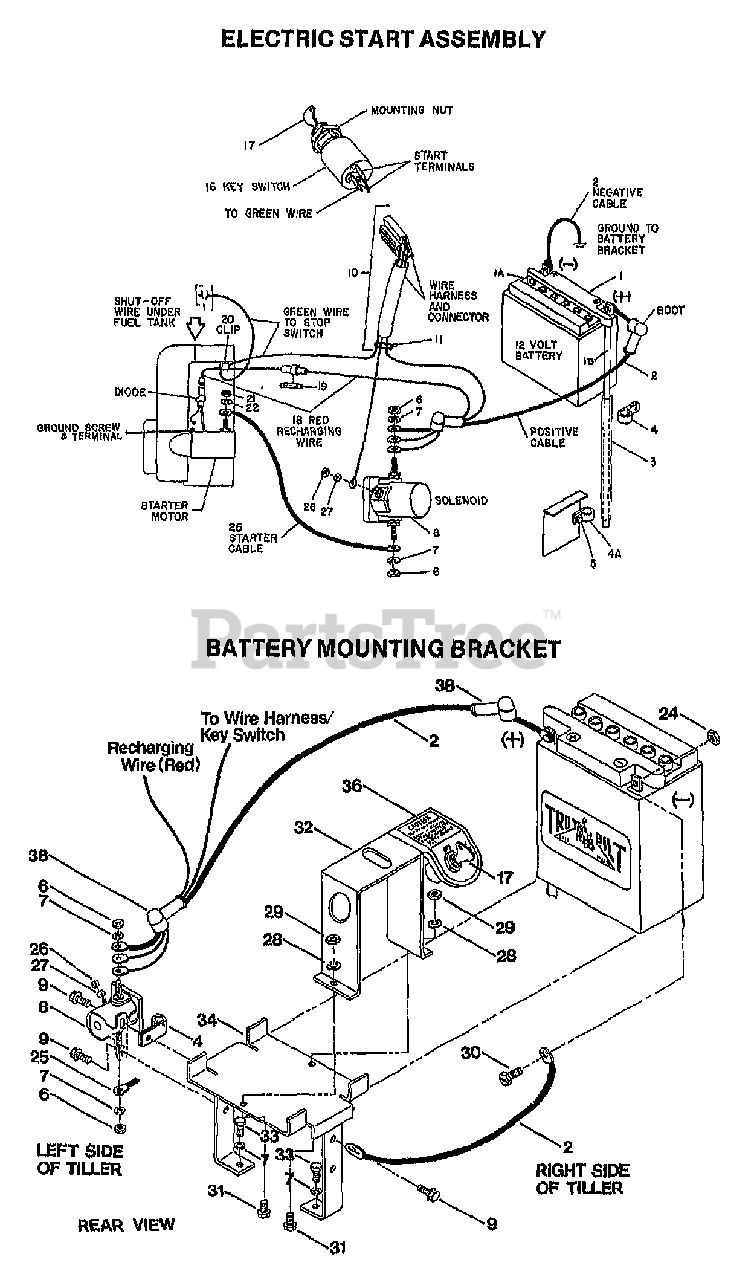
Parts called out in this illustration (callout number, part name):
1	BATTERY (INCL. HARDWARE TO CONNECT BATTERY CABLE TERMINALS TO BATTERY POSTS)
1A	CAP-YELLOW
1A	CAP-BATTERY WHITE (PONY)
1B	TUBE-VENT BATTERY/HSE
2	CABLE-BATTERY (REPLACES #9223)
3	TUBING-RUBBER
4	CLAMP (SMALL)
4A	CLAMP (LARGE)
5	SCR-HHC 5/16-18X.75 GR 5 ZP
6	NUT-HEX 5/16-24
7	WASHER-LK .312 ZP
8	KIT-SOL W/HDW (INCL. NUTS & WASHERS FOR CABLE AND WIRES)
9	SCR-HWH 1/4-20 X .5 STH
10	ASSM-HARNESS 2647/20857
11	TIE-TWIST LOCK
16	KEYSWITCH W/KEYS
17	KEYS(1 PAIR) FOR SWITCH
18	WIRE-RECHARGE 5&7 BRIGGS
19	FUSE-3 AMPERES
20	CLIP-SPECIAL
21	NUT, HEX #10-24 (NOT AVAIL.FROM GARDEN WAY)
22	LOCKWASHER, #10 (NOT AVAIL. FROM GARDEN WAY)
24	NUT, CABLE TO BATTERY (USE #9800 OR EQUIV.)
25	CABLE-STARTER
26	NUT-HH M10-32X.125
27	WASHER-EXTERNAL TOOTH 1
28	WASHER-LK .25 ZP
29	NUT-HEX 1/4-20 ZP
30	BOLT, HEX (USE #9775 OR EQUIV.)
31	SCR-CARR 1/4-20X1.25
32	PLTE-KEYSWITCH W/DEC-PONY 3 (INCL. #20418)
33	SCR-HH 5/16-18X1.0 G5 ZP
34	BRKT-BATTERY PNT
36	DECAL-KEYSWITCH TILLER
